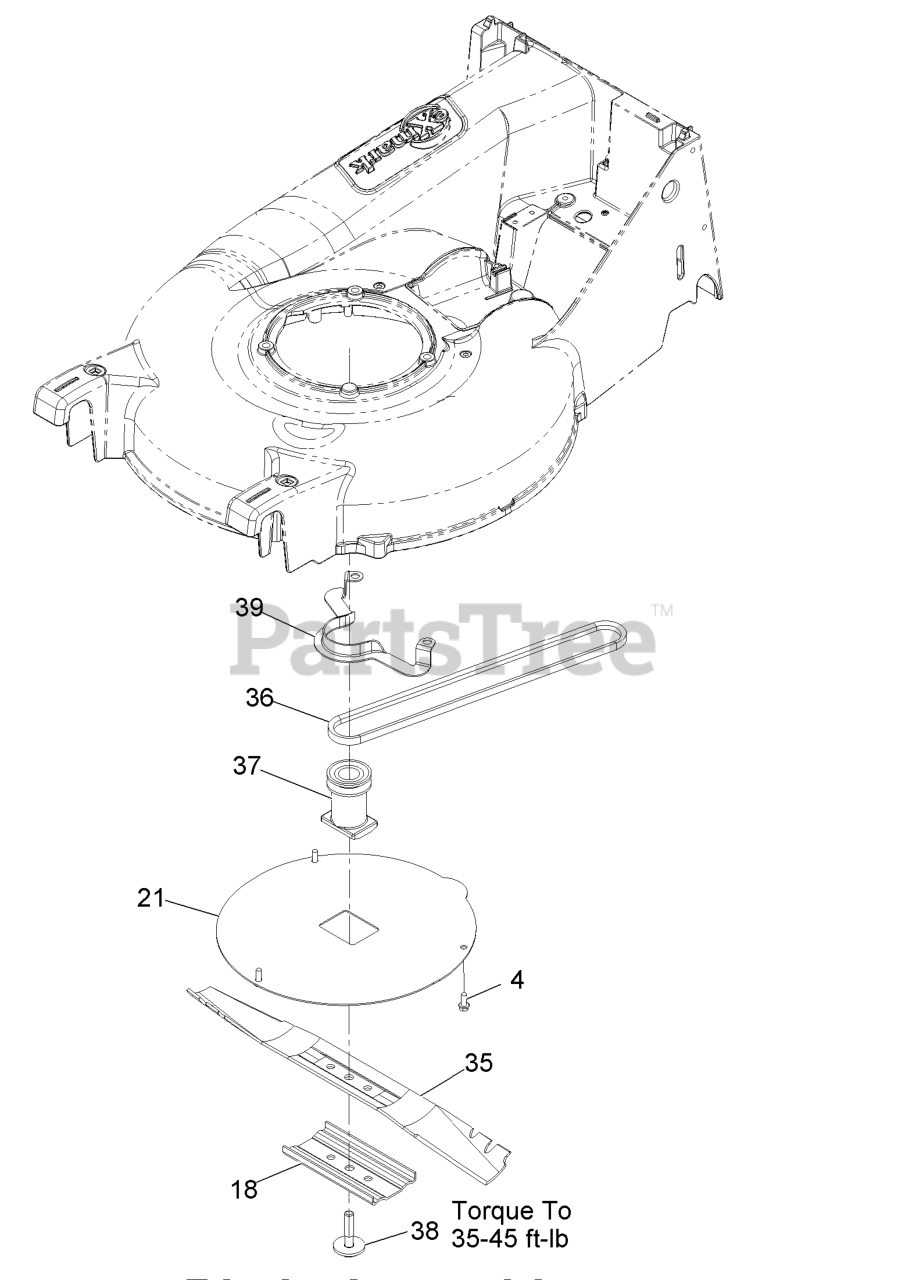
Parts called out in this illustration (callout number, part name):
4	SCREW-HWH
18	SUPPORT-BLADE
36	BELT,3L P21 DRIVE
37	BLADE-ADAPTER
38	BOLT-BLADE, SEM
39	GUIDE-BELT
